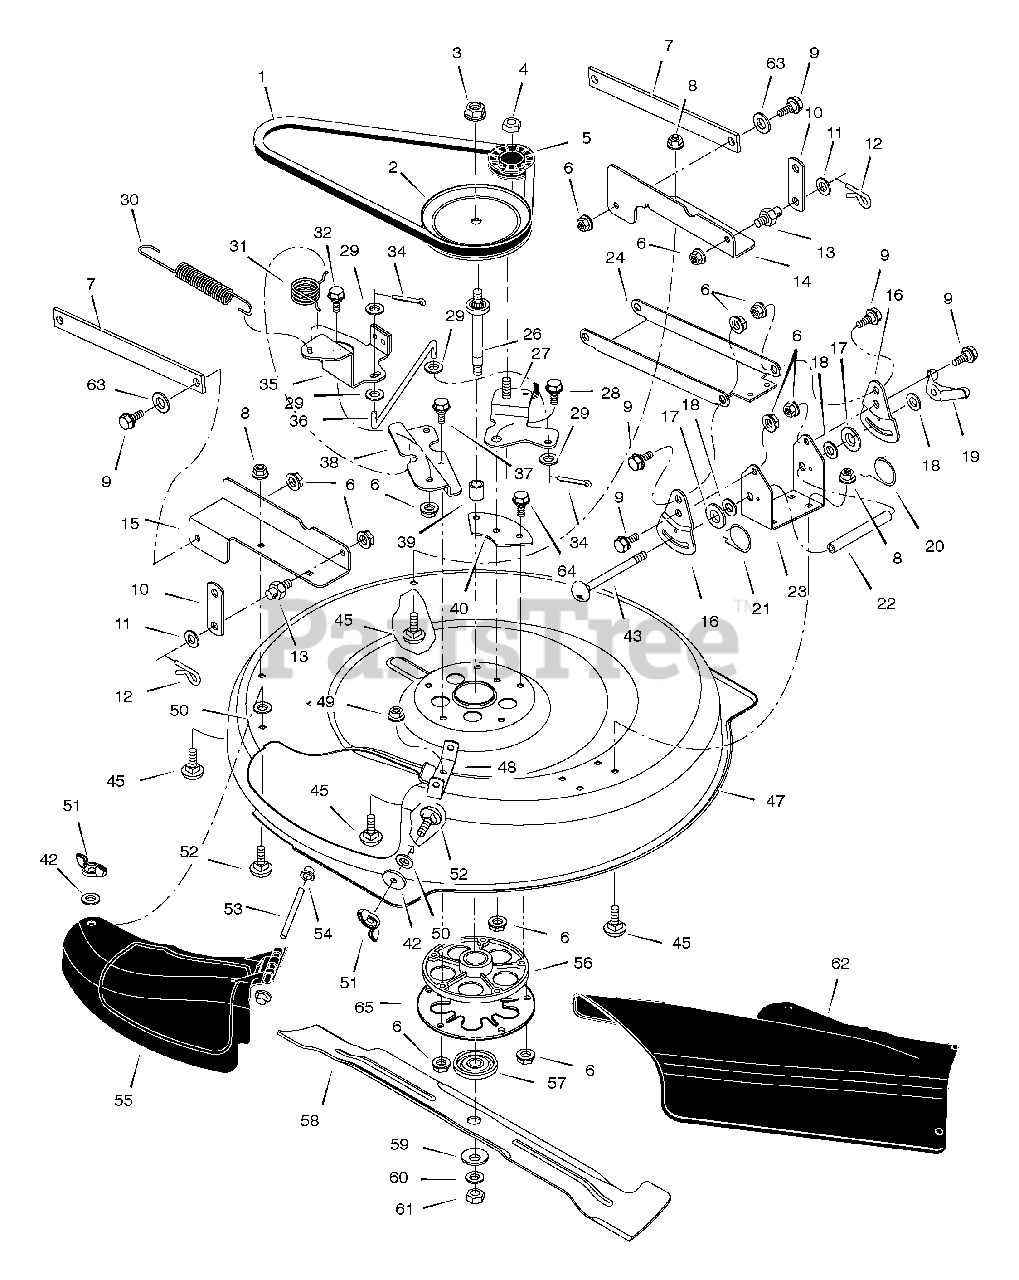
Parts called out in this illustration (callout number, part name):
1	Belt, Blade Drive
2	Pulley, Input
3	Locknut
4	Nut, Flange
5	Pulley, Idler
6	Nut, Flange
8	Nut, Flange
9	Bolt, Shoulder
10	Link, Lift
11	Washer
12	Pin, Hair
13	Pin, Threaded Shoulder
14	Bracket, Left Rear
15	Bracket, Right Rear
16	Plate, Adjustment
17	Pad, Friction
19	Wingnut
20	Spring, Left Torsion
21	Spring, Right Torsion
22	Tube, Spacer
23	Bracket, Deck
24	Hanger, Front
26	Shaft, Splined
27	Arm Assembly , Idler
28	Bolt, Shoulder
29	Washer
30	Spring, Extension
31	Spring, Torsion
32	Bolt, Shoulder
34	Pin, Cotter
35	Arm Assembly, Brake
36	Link, Idler Arm
37	Bolt
38	Bracket, Brake Mounting
39	Spacer, Jackshaft
40	Plate, Idler Mounting
43	Bolt, Carriage
45	Bolt, Carriage
47	Housing, Blade
48	Hinge, Mulching Cover
49	Nut, Flange
50	Nut, Speed
51	Wingnut
52	Bolt, Carriage
53	Rod, Chute Deflector
54	Cap, Push
55	Cover, Mulch
56	Mandrel Housing
57	Adapter, Blade
59	Washer, Cup
61	Nut, Blade Mount
62	Deflector, Chute
63	Bolt, Carriage
64	CAPSCREW, Hex Head, 5/16-18 x 1
65	Plate, Jackshaft Support
